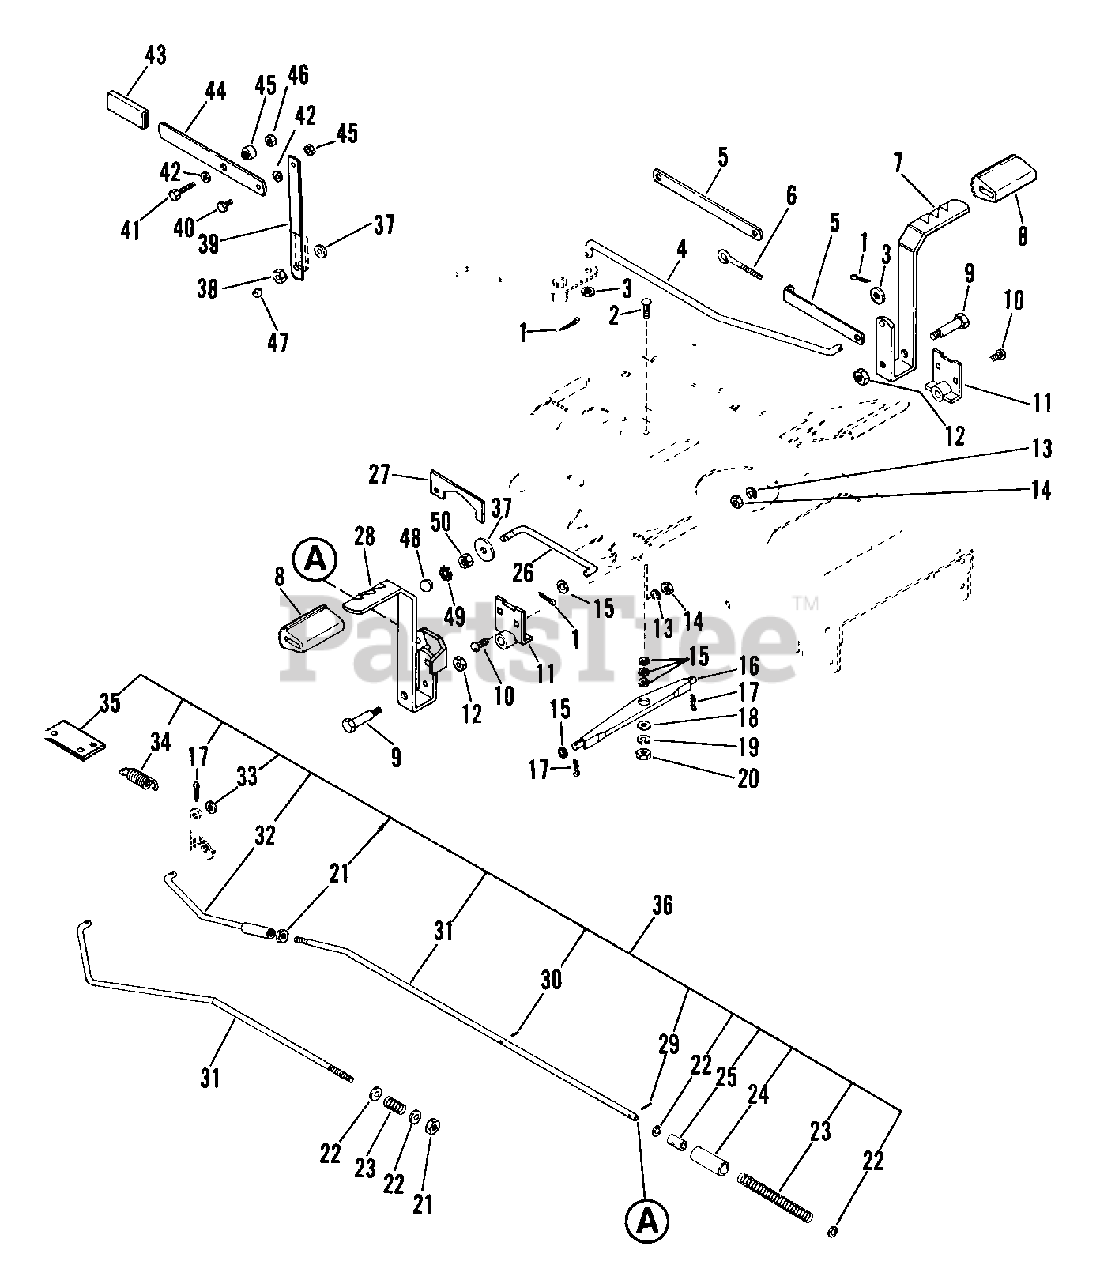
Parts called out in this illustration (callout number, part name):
1	PIN-COTR .12X.75 PL
2	BLT-RDHDSQNK .38-16X1.25 PL
3	WSHR-FL-STL .438X1.0X.083 PL
4	CLUTCH ROD
5	LINK
5	EYE-BOLT
7	CLUTCH PEDAL
8	PEDAL COVER
9	SHOULDER BOLT .50 X 1.75
10	BLT-RDHDSQNK .31-18X.75 GR5 PL
11	PEDAL PIVOT
12	NUT-LK-JAM-CTR .375-16 PL
13	WSHR-LK .312X.097 PL HVY
14	NUT-HEX .312-18
15	WSHR-FL-STL .380X.626X.033
16	PIVOT ARM
17	PIN-HAIR INT .08X.18X1.18
18	WSHR-FL-STL.406X.812X.065PL
19	WSHR-LK .375X.115 HVY PL
20	NUT-HEX .375-16
21	NUT-LK .312-18 GR A PL
21	NUT .375-24 PL
22	WSHR-FL-STL .38X.875X.083 PL
23	SG-COMP .102X.85X1.031
23	SG-COMP .106X.63X 12.0 WLD 62
24	SLEEVE
25	SLEEVE
26	PARKING BRAKE ROD
28	BRAKE PEDAL
29	PIN-ROLL .125X.88
30	PIN-ROLL .125X.50
31	BRAKE ROD
32	BRAKE ROD
33	WSHR-FL-STL .323X.625X.062 PL
34	SG-TENS .072X.75X2.81 WLD ??
35	ANCHOR PLATE
36	BRAKE LINKAGE ASSEMBLY
37	WSHR-FL-STL .406X1.50X.049PL
38	NUT-LK-JAM-CTR .375-16 PL
39	LINK
40	BLT-HEX .25-20X.63 PL GR2
41	BLT-HEX .25-20X1.50 PL GR5
42	WSHR-FL-STL.281X.62X.065 PL
43	GRIP
44	ARM
45	SPACER-SHOULDER
46	NUT-LK-CTR .250-20 PL
47	GRIP
48	SHIFT BALL
49	WSHR-LK-EXT .375X.035 PL
50	NUT-JAM .375-16 PL
